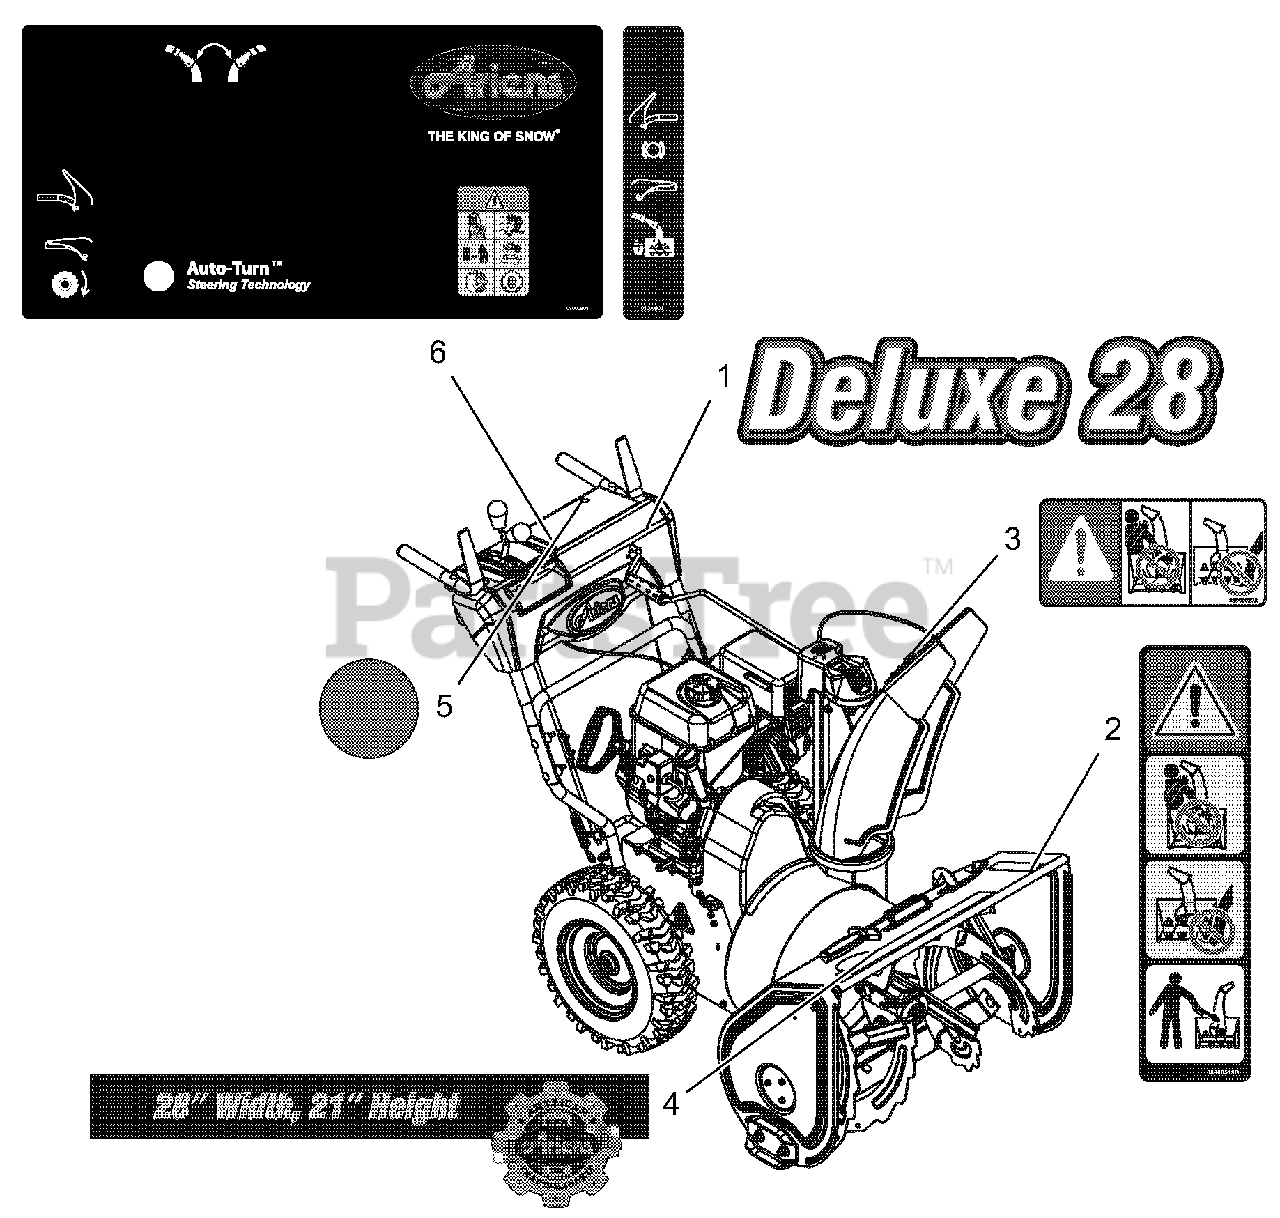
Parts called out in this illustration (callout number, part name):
1	DECAL, DELUXE 28 SM DASH
2	DECAL, DANGER - ROTATING PARTS
3	DECAL, DANGER
5	DECAL,AUTODIFFERENTIAL
6	DECAL, CONTROL PANEL
